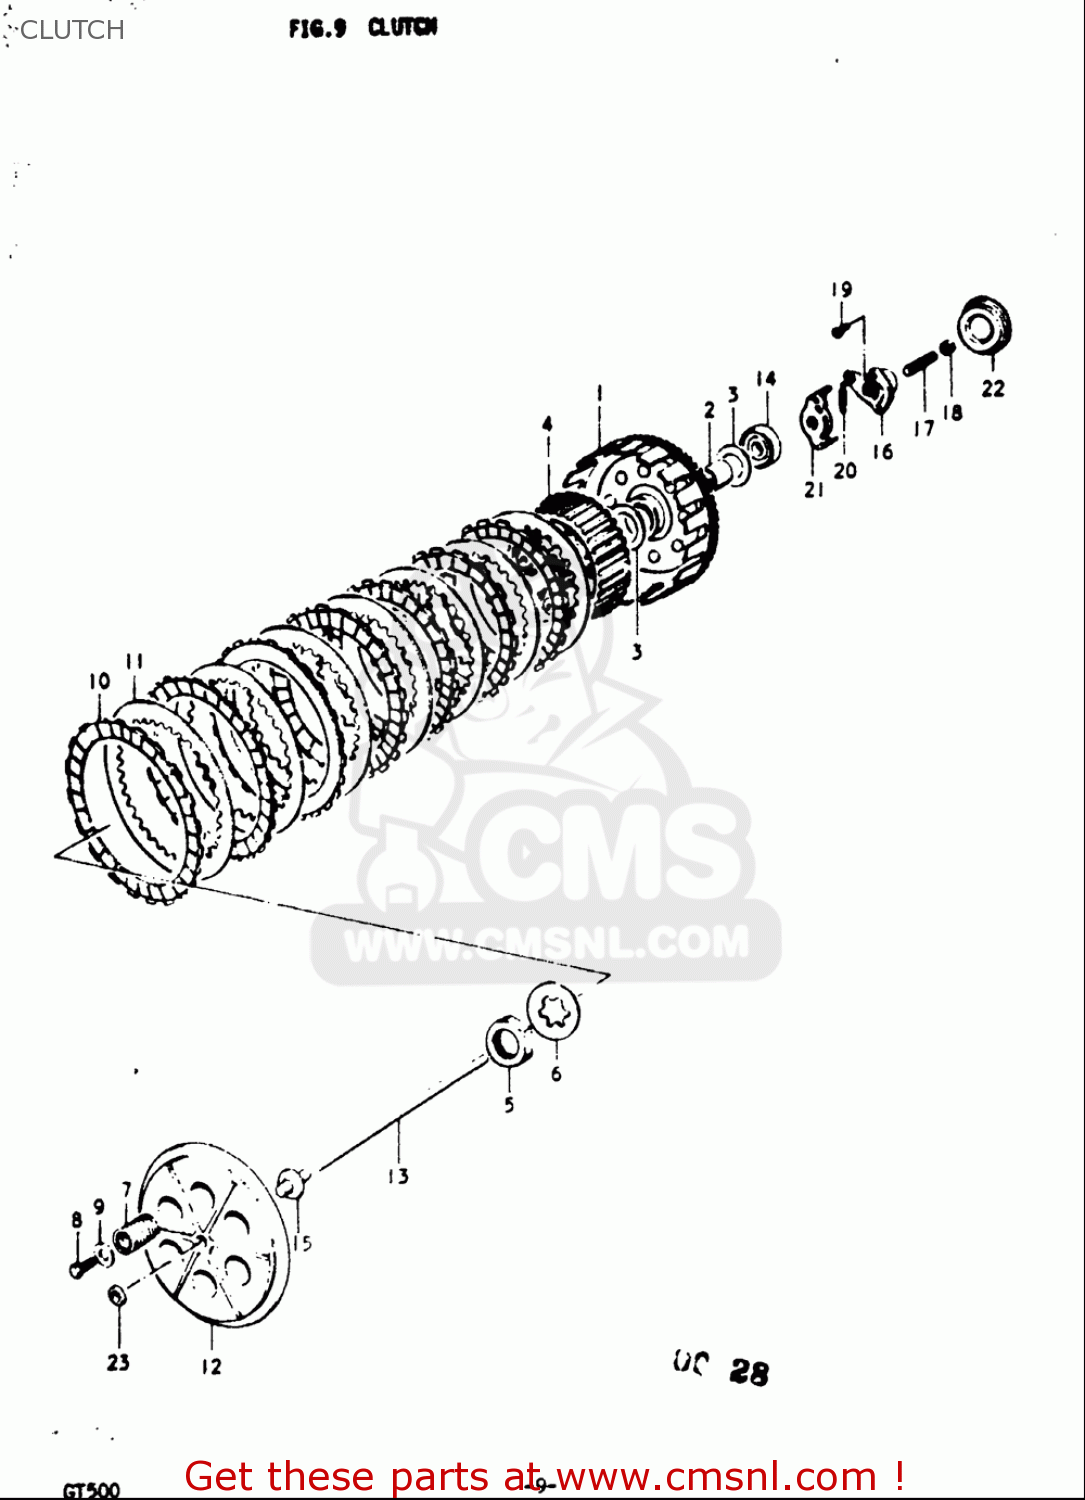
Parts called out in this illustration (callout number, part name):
2	SPACER
3	WASHER
5	NUT
6	WASHER,LOCK
7	SPRING
8	BOLT
9	WASHER(6.5X20X1.6)
10	PLATE,CLUTCH DRIVE(T:3.5) (NAS)
11	PLATE,CLUTCH DRIVEN(T:2.0) (NAS)
14	SEAL,OIL(8X32X6.5)
17	SCREW
18	NUT
19	SCREW
20	SPRING
22	CAP(OD:36)
23	SEAL,OIL (10X17X5)
